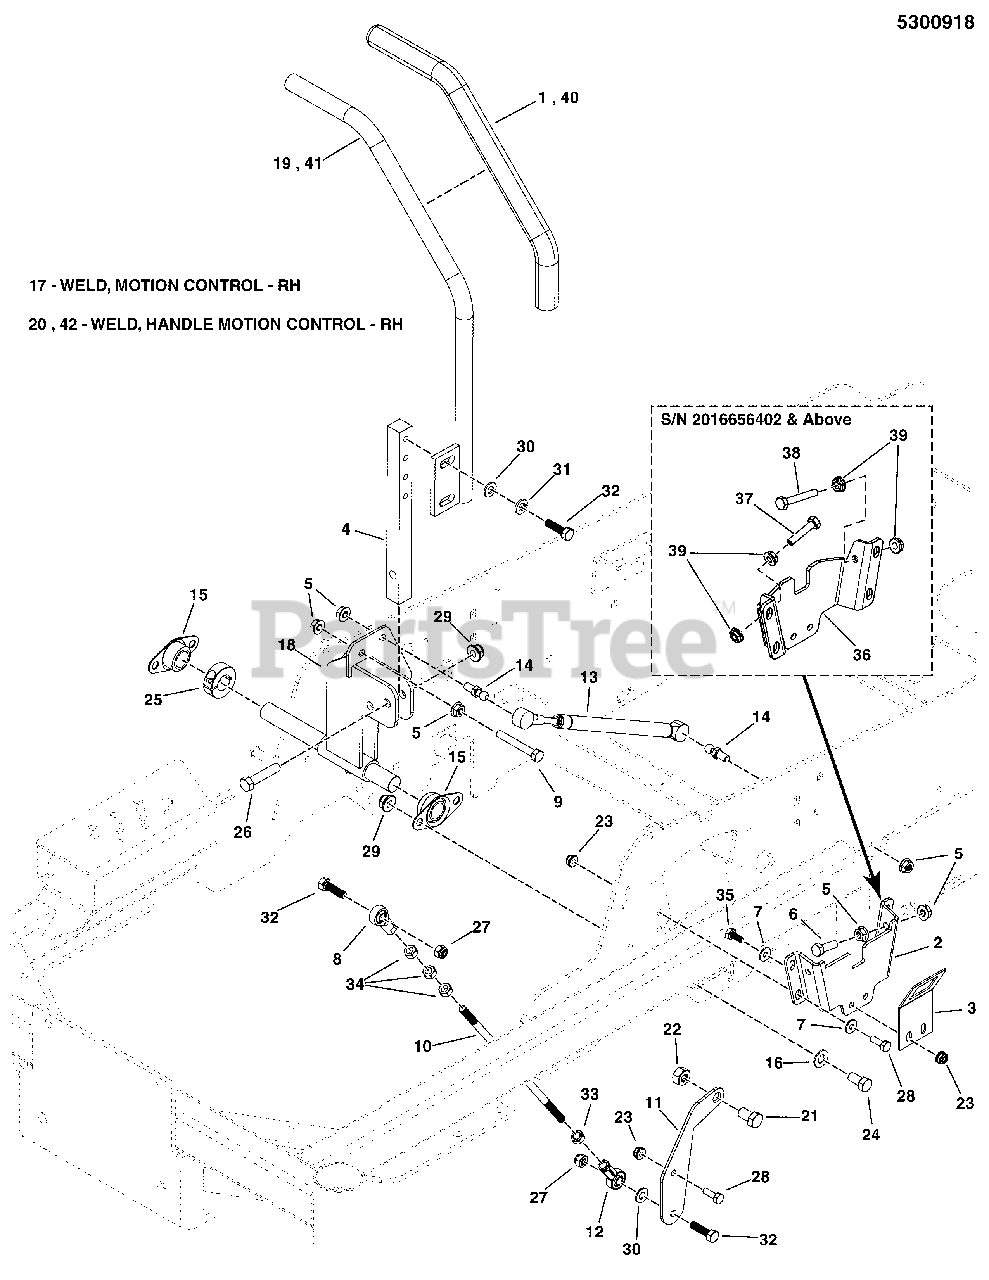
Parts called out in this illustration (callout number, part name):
1	GRIP, FOAM, 3/4 ID, 16 LONG
2	NEUTRAL LOCK, SNAPPER PRO 36-44 - BLK
3	SWITCH PLATE, MOTION CONTROLS - BLK
4	MOUNT, CONTROL ARM
5	NUT, 5/16-18 HEX SERRATED FLANGE (SMALL)
6	BOLT, 5/16-18 X 1 GD5 YZ
7	WASHER, 1/4 SAE (5025154)
8	BALL JOINT 5/16-24 RH FEMALE STAMPED STL
9	BOLT, 5/16-18 X 2-1/4" GD5 YZ
10	ROD, HYDRO LINKAGE
11	PLATE, CONTROL TRANSAXLE - BLK
12	BALL JOINT 5/16-24 LH FEMALE STAMPED STL
13	DAMPENER, CONTROL,#(P6709/P3610)
14	BALL STUD, 5/16 X .50,# PC-477-2)
15	BEARING, BRONZE FLANGE, 3/4
16	WASHER, 3/8 SAE
17	WELD, MOTION CONTROL, RH - BLK
18	WELD, MOTION CONTROL, LH - BLK
19	WELD, HANDLE MOTION CONTROL, LH - BLK
20	WELD, HANDLE MOTION CONTROL, RH - BLK
21	BOLT, 7/16-14 X 3/4, GD 5 YZ
22	NUT, 7/16-14 HEX TOP LOCK
23	NUT, 1/4-20 HEX NYLOCK FLANGE (5025391)
24	BOLT, 3/8-16 X 3/4 GD5 YZ
25	COLLAR, 3/4" SPLIT
26	BOLT, 3/8-16 X 1-3/4 GD5
27	NUT, 5/16-18 HEX NYLON LOCK
28	BOLT, 1/4-20 X 3/4 GD5 YZ
29	NUT, 3/8-16 HEX NYLOCK FLANGE
30	WASHER, 5/16 SAE
31	WASHER, 5/16 LOCK YZ
32	BOLT, 5/16-18 X 1-1/8 GD5
33	NUT, 5/16-24 HEX, LH
34	NUT, 5/16-24 HEX
35	BOLT,1/4-20X5/8
36	NEUTRAL LOCK, 50XT - BLK
37	BOLT, 1/4-20 X 1-1/4 GD5 TFL
38	BOLT, 1/4-20 X 1-3/4 GD5 TFL
39	NUT, 1/4-20 HEX SERR. FLANGE
40	GRIP, FOAM, 1" ID, 16" LONG
41	WELD, HANDLE MOTION CNTRL, 17.0, 1.0, LH - BLK
42	WELD, HANDLE MOTION CNTRL, 17.0, 1.0, RH - BLK
